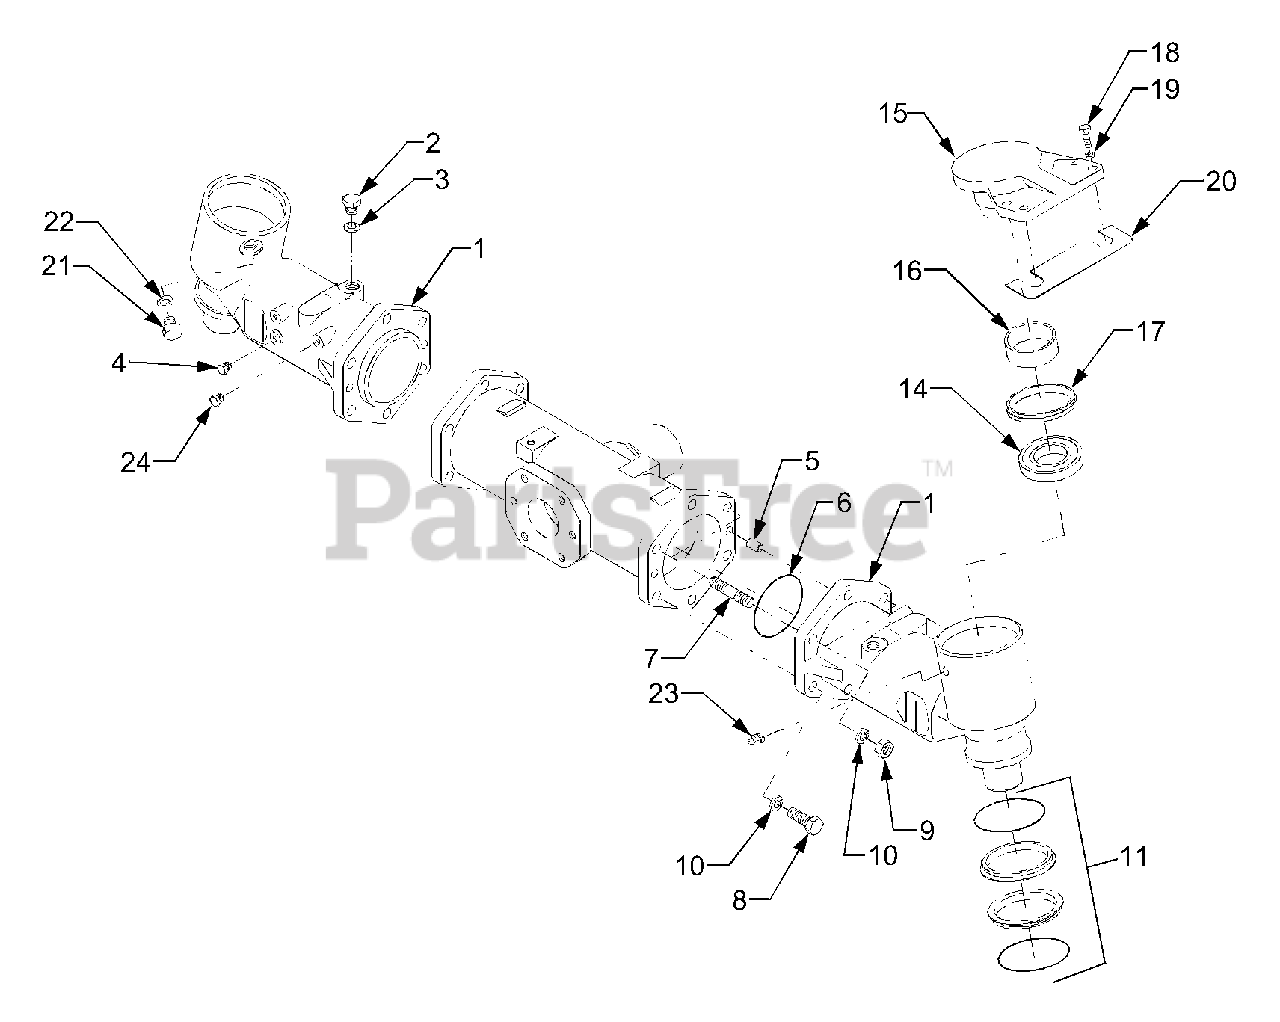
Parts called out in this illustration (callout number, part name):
1	Case, Bevel Gear
5	Pin, Straight
10	Washer, Spring
11	Floating Seal Ass'y
14	Bearing, Ball
15	Support, Axle Case
19	Washer, Spring
23	Nipple, Grease
